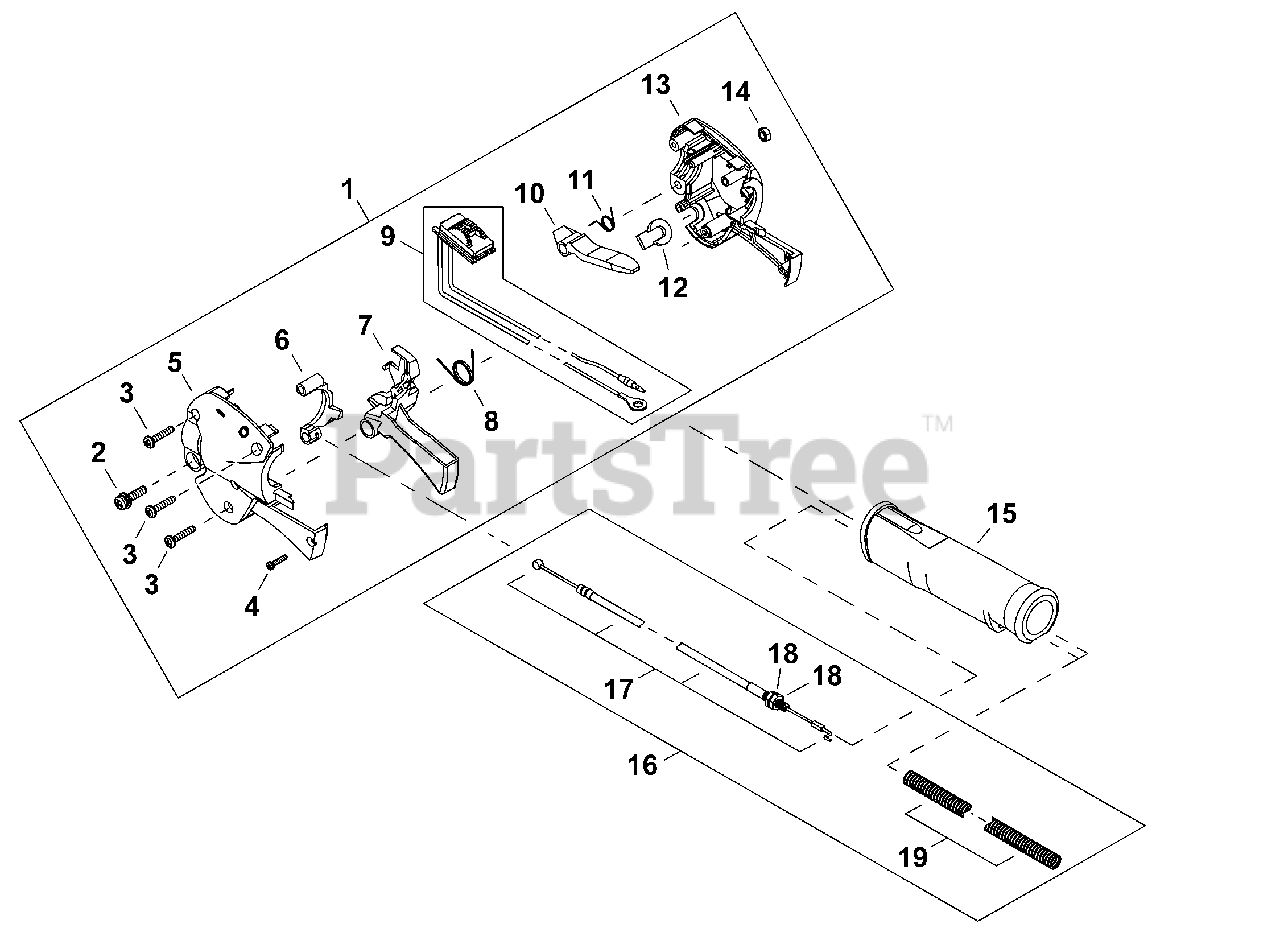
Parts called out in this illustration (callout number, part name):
1	THROTTLE CONTROL ASSY
2	SCREW M5×20
3	SCREW, TAPPING M4×20
4	SCREW, TAPPING 3×14
5	CONTROL HANDLE - LEFT
6	LOCKOUT, THROTTLE
7	TRIGGER, THROTTLE
8	SPRING, THROTTLE RETURN
9	SWITCH, ON-OFF
10	LEVER, THROTTLE LOCKOUT
11	SPRING, THROTTLE LOCKOUT
13	CONTROL HANDLE - RIGHT
15	GRIP, REAR
16	CABLE ASSY, THROTTLE
17	CABLE, THROTTLE
19	TUBE, PLASTIC PROTECTIVE
